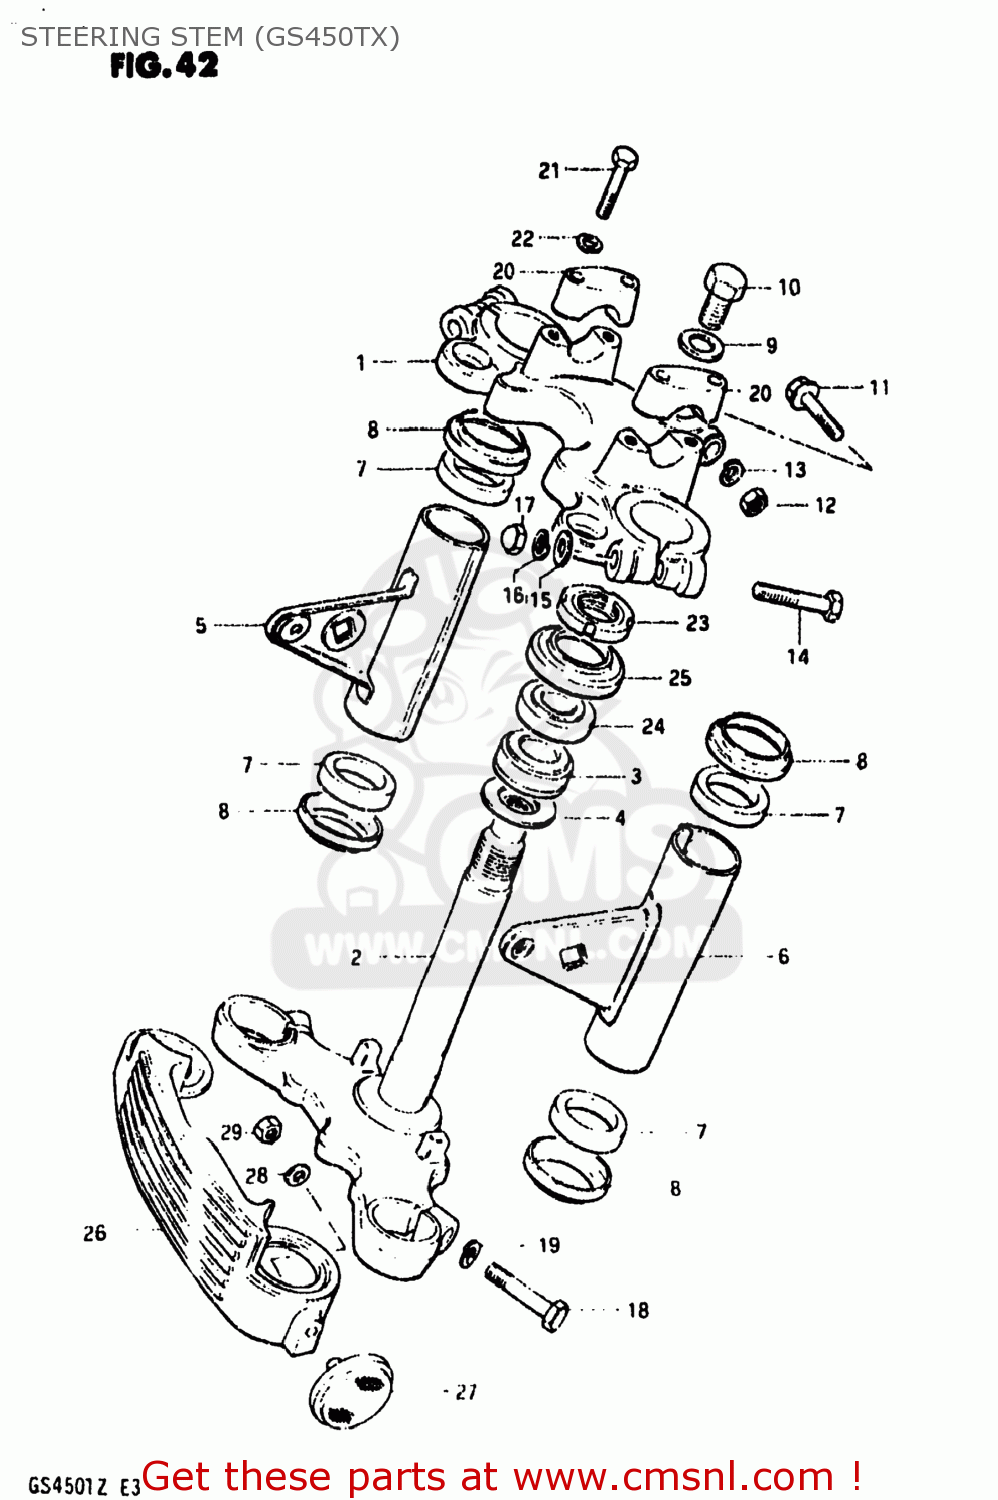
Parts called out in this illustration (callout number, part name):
1	HEAD,STEERING STEM
2	STEM,STEERING
3	BEARING
4	WASHER,THRUST
5	BRACKET,HEADLAMP,RIGHT
6	BRACKET,HEADLAMP,LEFT
7	CUSHION,HEADLAMP BRACKET
8	CAP,HEADLAMP BRACKET
9	WASHER
10	BOLT(12X20)
11	BOLT
12	NUT
13	LOCK WASHER
14	BOLT 10X55
15	WASHER
16	LOCK WASHER
17	NUT
18	BOLT 10X40
19	LOCK WASHER
20	HOLDER,HANDLE UPR
21	BOLT
22	WASHER,LOCK,8.
23	NUT,STEERING STEM(25X44X10)
24	TAPER,ROLLER BEARING
25	DUST SEAL,STEERING,UPPER
26	COVER,FRONT FORK
27	REFLEX REFLECTOR,RR
28	WASHER
29	NUT
